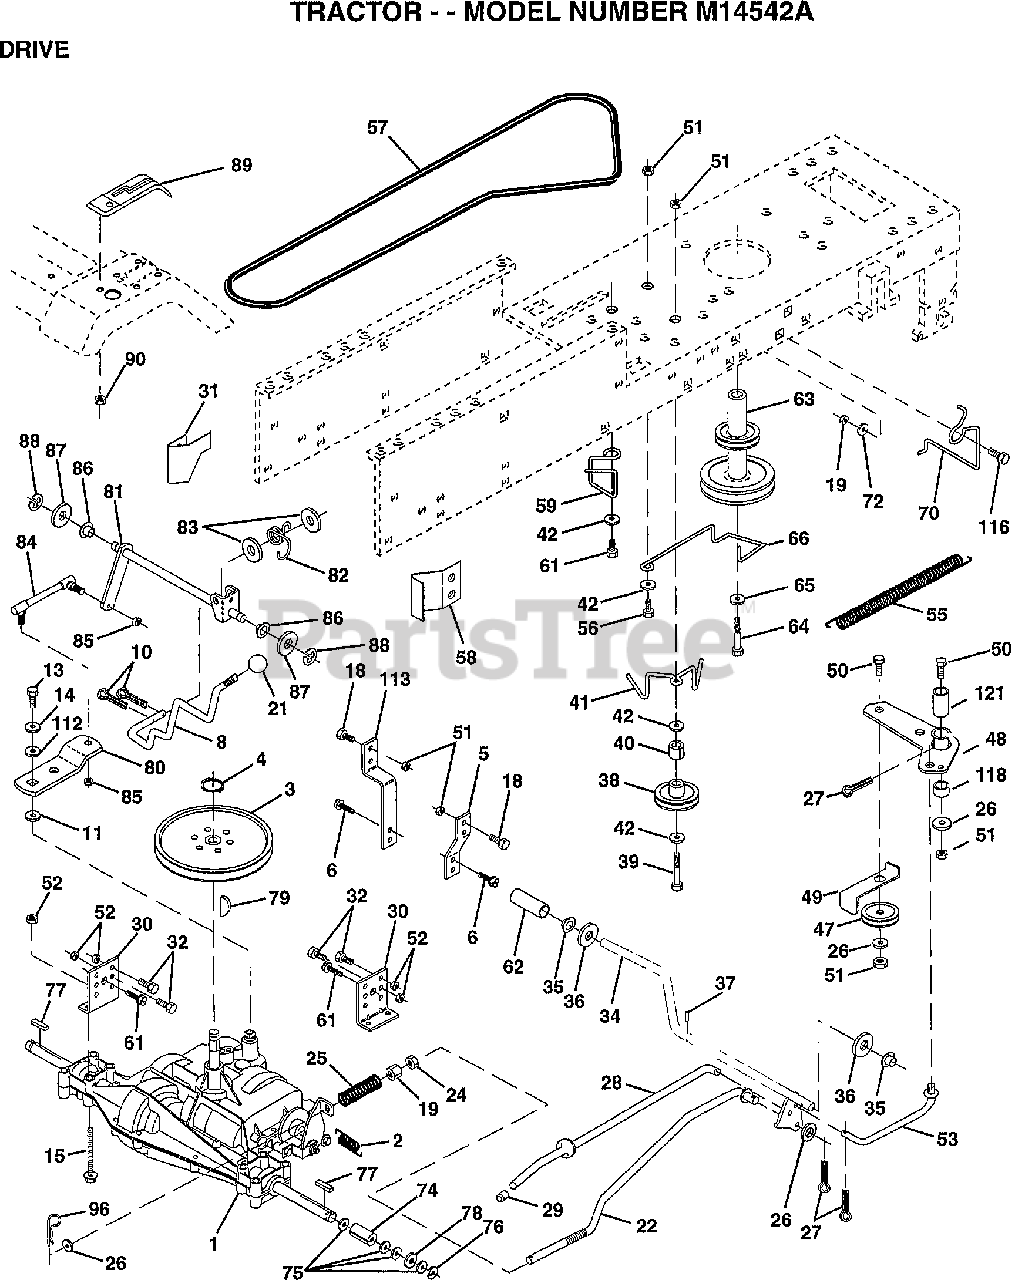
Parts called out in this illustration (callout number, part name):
1	TRANSAXLE, PEERLESS
2	SPRING.BRAKE.RETU
3	PULLEY TRANSAXLE 18" TIRES
5	STRAP TORQUE
6	SCREW
8	ROD SHIFT FEND LT
10	PIN COTTER 1/8
11	WASH-SHFT PLT LT
13	BOLT.1/4-28.W/PAT
14	LOCKWASHER
15	BOLT.HX.FLG.5/16
18	BOLT
21	KNOB T (1/2-HOLE)
22	BRAKE ROD
24	NUT
25	SPRING ROD LT
26	WASHER
27	COTTER PIN
28	ROD.BRAKE.PARK.LT
29	PLUNGER CAP T
30	TRANSAXLE MTG BKT
31	"KEEPER,BELT LH T"
32	BOLT
34	SHAFT ASM-PEDAL F
36	WASHER LT
38	PULLEY.IDLER.FLAT
39	BOLT
40	SPACER T
42	WASHER
48	BELLCRANK ASM
49	RETAIN BELT
53	"LINK, CLUTCH T"
55	"SPRING, RETURN LT"
58	"KEEPER,BELT RH T"
59	KEEPER BELT CNTSP
61	SCREW
62	PEDAL COVER T
63	PULLEY.ENGINE
64	BOLT
65	LOCKWASHER
66	KEEPER-BELT
70	KEEPER BELT ENG
72	WASHER
74	SPACER AXLE
75	WASHER
76	E-RING LT
77	SQUARE KEY
78	WASHER
80	"ARM.SHIFT.20""TIRE"
81	SHAFT.CROS.P930.
82	"SPRING,TORSION"
83	WASHER
84	"ROD.TIE.20""P930LT"
85	NUT.CNT.LOCK.1/4
86	BUSHING
87	WASHER D
88	KLIP RING
90	NUT
96	SPACER T
112	WASHER LT
113	"STRAP,TORQUE"
116	BOLT RDHD 3/8-16
118	SPACER-BELLCRANK
121	NYLINER-CLUTCHING
